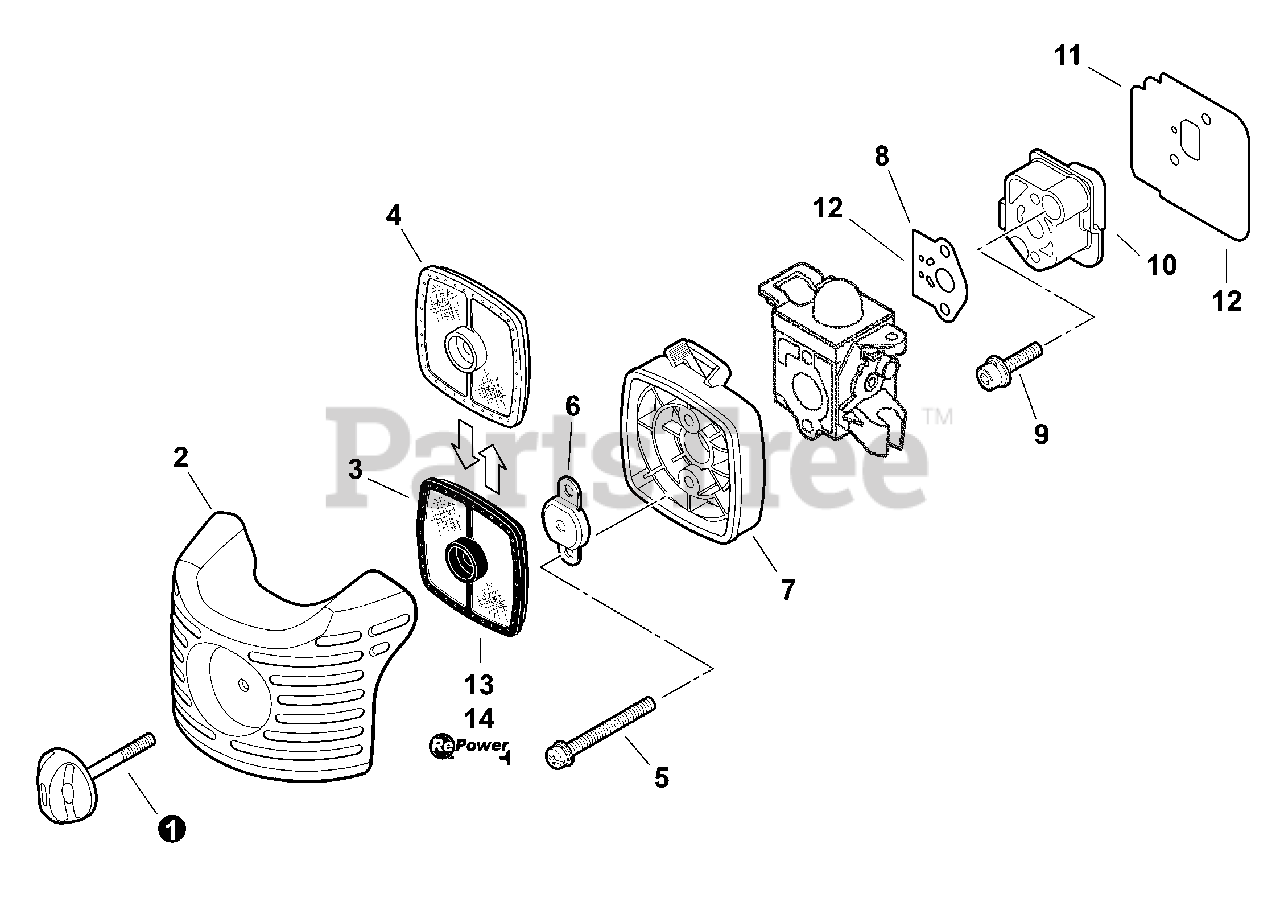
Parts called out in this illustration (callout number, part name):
1	THUMBSCREW
2	COVER, AIR FILTER
3	FILTER, AIR - DOUBLE LAYER
4	FILTER, AIR - SINGLE LAYER
5	SCREW - 5×65
6	PLATE, PREVENT
7	CASE, AIR FILTER
8	GASKET, INTAKE
9	INSULATOR, INTAKE
10	SCREW - 5×25
11	SHIELD, INTAKE
12	GASKET KIT
13	RePower FILTER KIT
14	RePower TUNE-UP KIT
